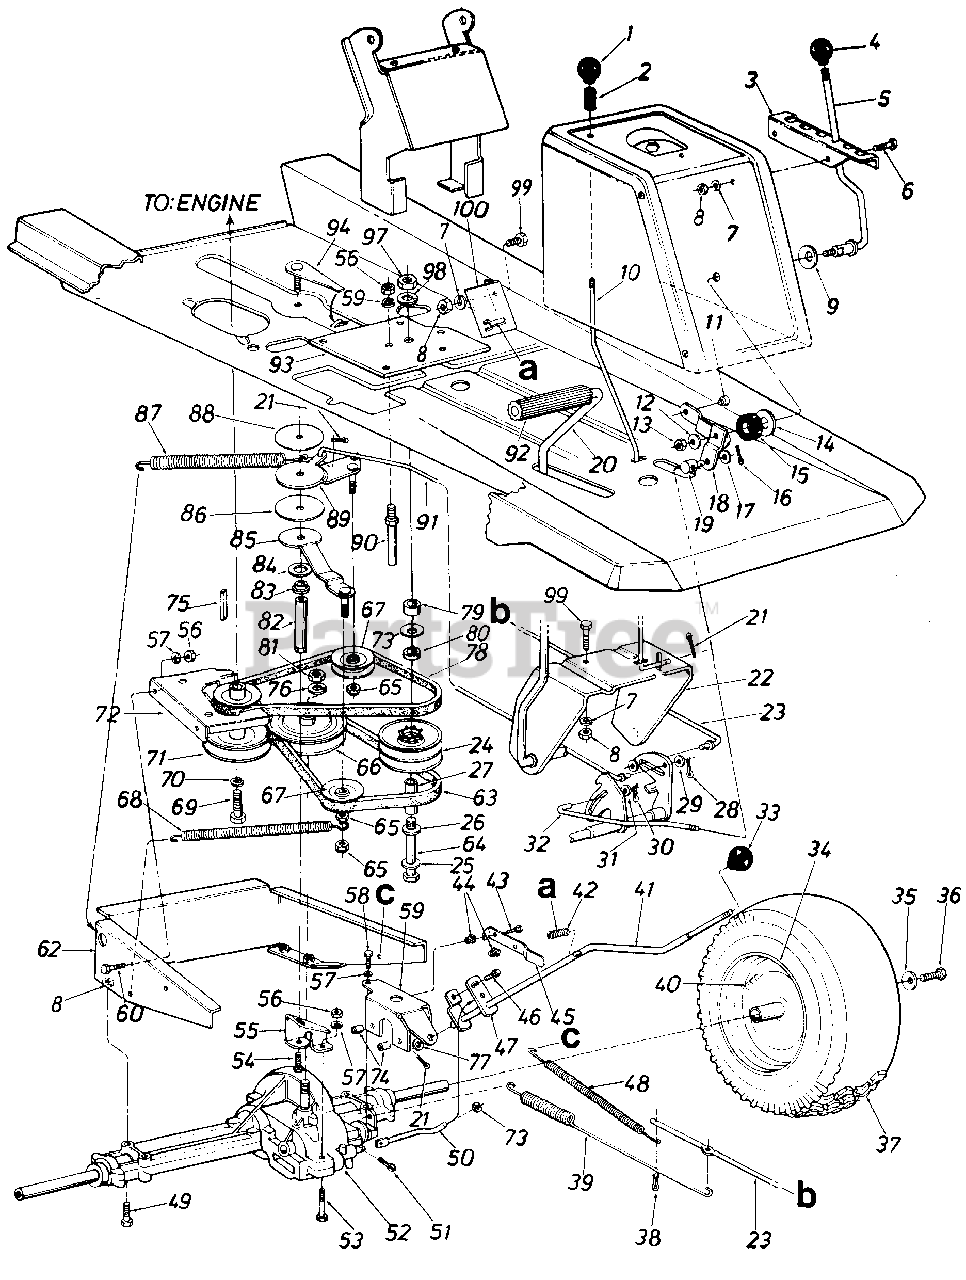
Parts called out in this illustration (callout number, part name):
1	Ball Knob 1/4-20 Thd. 1.25"
2	Compression Spring
5	Speed Control Lever
6	Truss Mach. Scr. 5/16-18 x .75" Lg.
7	L-Wash. 5/16" I.D.
8	Hex Nut 5/16-18 Thd.*
9	Bell-Wash. .345" I.D. x .88"
10	Brake Locking Rod
12	Bell-Wash. .345" I.D. x .08"
13	Hex Cent. L-Nut 5/16-18 Thd.
14	Fl-Wash. .531" I.D. x 1.25 O.D.
15	Rubber Washer
16	Intern. Cotter Pin 1/2" Dia.
17	Fl-Wash. .34" I.D. x .68" O.D.
18	Speed Control Lever Brkt. Ass'y.
19	Ferrule-Engagement
20	Clutch/Brake Pedal Ass'y.
21	Cotter Pin 3/32" Dia. x .75"
22	Clutch/Brake Pedal Ass'y.
23	Brake Rod
24	Variable Speed Pulley Ass'y.
25	Washer . 40" I.D. x 1. 2 5 " O.D.
26	Thrust Brg. 1.25" O.D. x .56" I.D.
27	Spacer Sleeve 2.71 "
28	Cotter Pin 1/8" Dia. x 1.25"
29	Fl-Wash. .34" I.D. x .60" O.D.
30	Intern. Cot-Pin 5/16 Dia.
31	Fl-Wash. .34" I.D. x .60" O.D.
32	Speed Control Rod
33	Ball Knob
34	Rear Wheel Rim Only
35	Bell-Wash. .345" I.D. x .88"
36	Hex L-Bolt 5/16-24 x .75" Lg.
37	Rear Wheel Ass'y.-Comp.
38	Cotter Pin 1/8" Dia. x 1.25"
39	Extension Spring 17.0" Lg.
40	Air Valve
43	C Sink ABS-Tap Scr. #8 x .50" Lg.
44	Push-in Nut #10
45	Spring Switch
46	Hex Bolt 1/4-20 x .50" Lg.
47	Shift Lever Adjusting Link
48	Ext. Spring 81/4" Lg.
49	3/16-18 x 2.50 Hex Bolt
50	Shift Rod
51	Intern. Cotter Pin
52	Transaxle
53	Hex Bolt 1/4-20 x 1.75" Lg.*
54	Hex Bolt 3/8-24 x .75" Lg.
55	Torque Rod Bracket
56	Hex Nut 1/4-20 Thd.
57	L-Wash. 1/4" I.D.
58	Self-Tap Mach. Scr. Type "C" 1/4-20 x 1.37" Lg.
59	Shift Lever Support Brkt.
60	Hex Bolt 1/4-20 x 1.00" Lg.
62	Transaxle Support Ass'y.
63	V-Belt
64	Hex Bolt 3/8-16 x 4.5" Lg.
65	Hex Ins. L-Nut 3/8-24 Thd.
66	5/8 V-Pulley .500" I.D. x 6"
67	V-Belt Idler .38" I.D. x 3.06"
68	Ext. Spring .50" O.D. x 6.37"
69	Hex Bolt 7/16-20 x 1.00" Lg.
70	L-Wash. 7/16" I.D.
71	Engine Pulley .500" O.D. & 3.56" O.D.
72	Upper Eng. Belt Guard
73	Bell-Wash. .4" I.D. x 1.12" O.D.
74	Spacel .256" I.D. x .50" O.D.
75	Sq.-Key 1/4" x 2.00" Lg.
76	L-Wash. 1/2" I.D.
77	Fl-Wash. .469" I.D. x .88" O.D.
78	V-Belt
79	Spacer 1.00" x .380" O.D.
80	Washer .56 I.D. x 1.25" O.D.
81	Hex Nut 1/2-20 Thd.
82	Torque Rod
83	Flange Bearing .378
84	Fl-Wash. .640" I.D. x 1.24"
85	Idler Bracket Ass'y.
86	Thrust Wash. .635" I.D.
87	Extension Spring 7.58" Lg.
88	Thrust Wash. .385" I.D.
89	Idler Bracket Ass'y. For Clutch
90	Belt Guard Pin 1/4" Dia.
91	Clutch Rod
92	Foot Pad
93	Mtg. Brkt. Variable Pulley
98	L-Wash. 3/8 Heavy Duty
99	Hex Bolt 5/16-18 x .75" Lg.
100	Shift Lever Spring Brkt.
